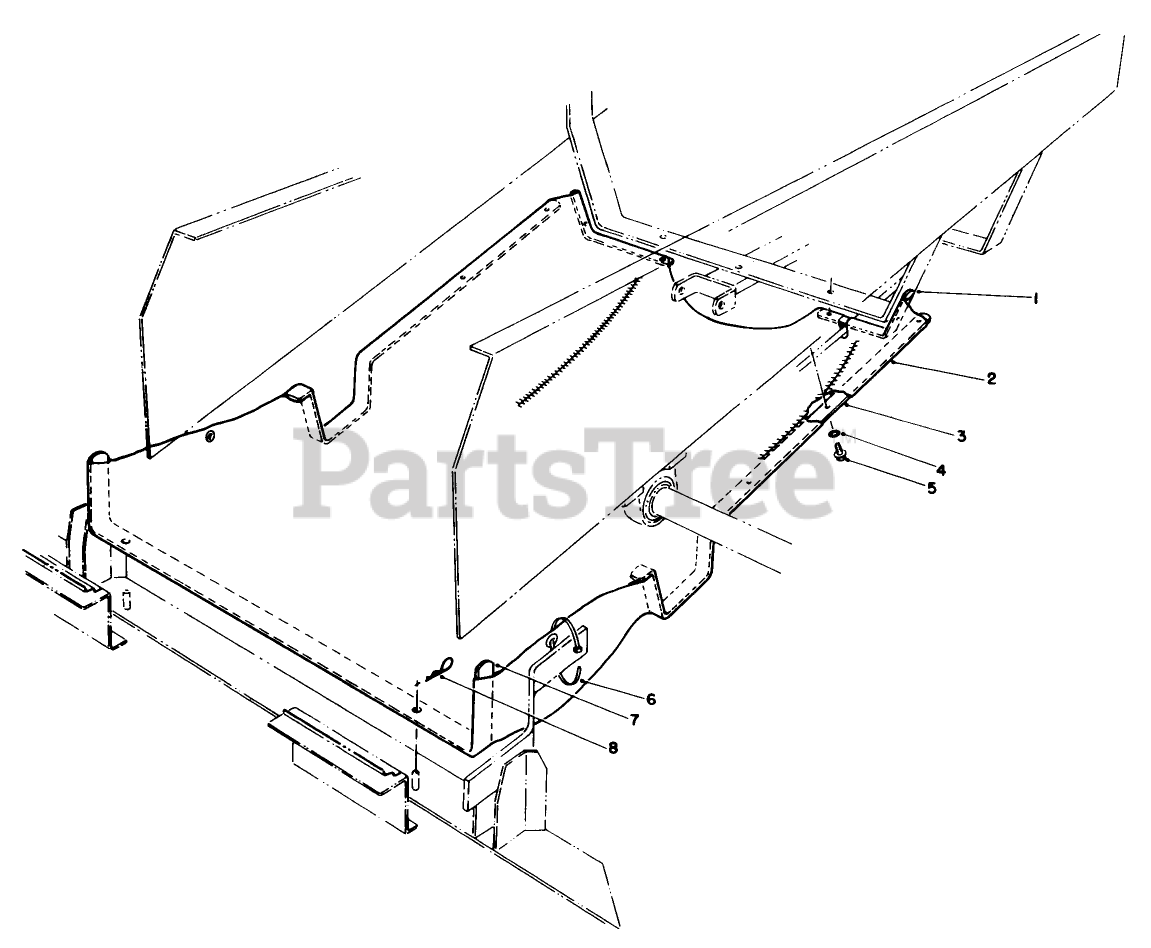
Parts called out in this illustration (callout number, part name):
1	SHIELD BRACKET R
2	CLOTH SHIELD
3	Support-Side
4	WASHER-LOCK
5	SCREW-HWH
6	TIE-CABLE
7	DECK SHIELD SUPPORT R
8	PIN-COTTER
